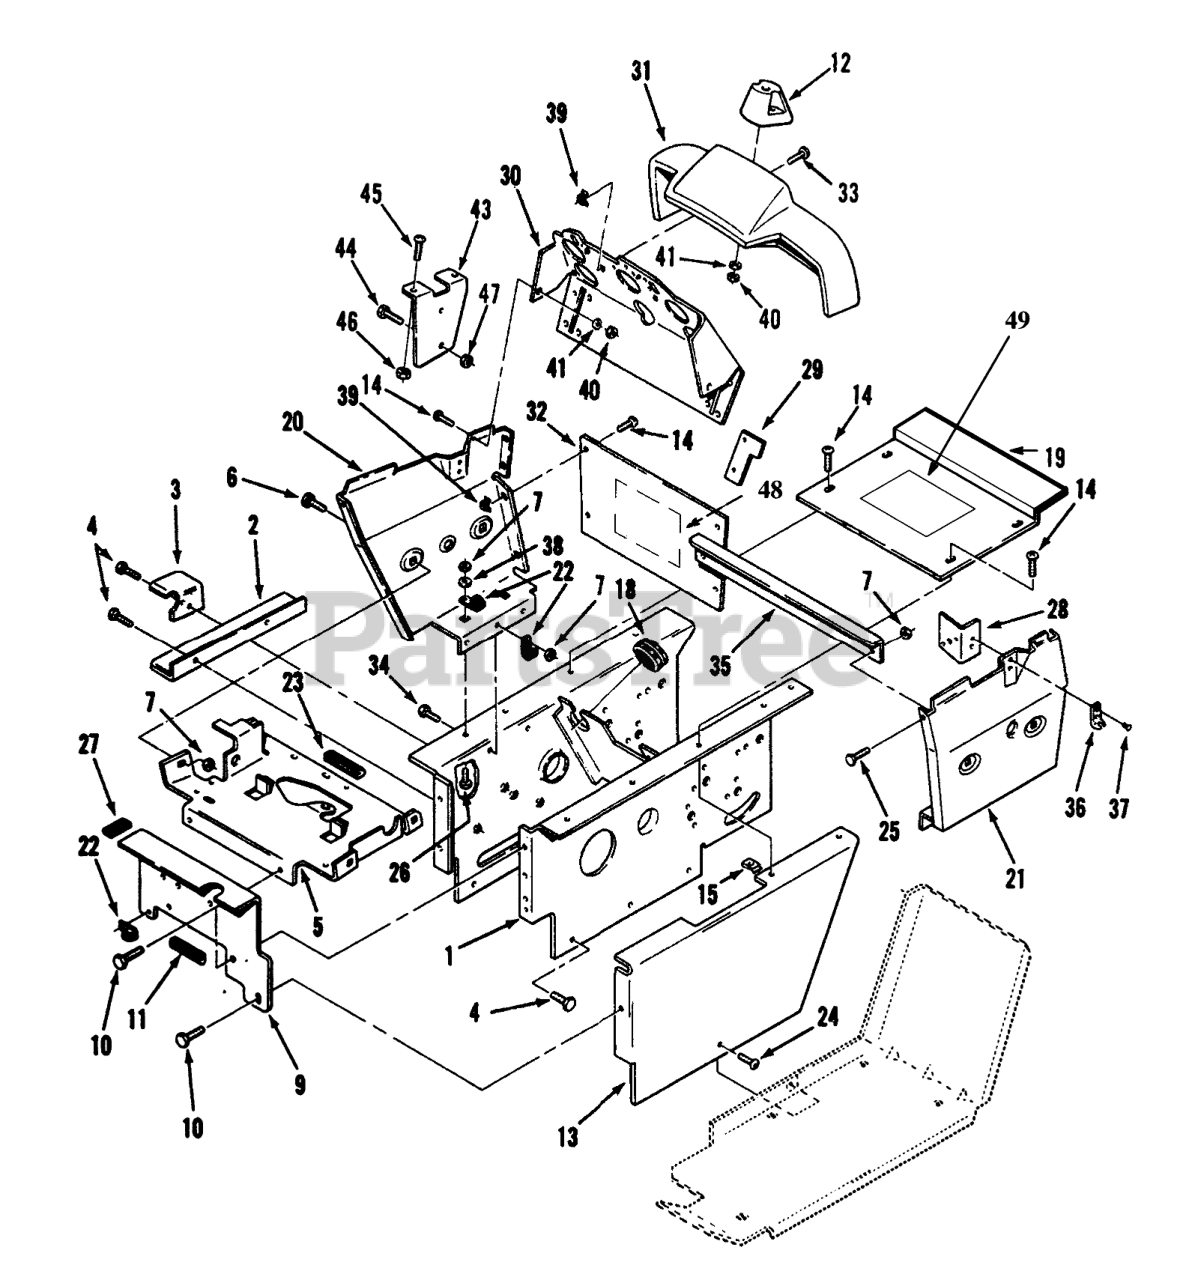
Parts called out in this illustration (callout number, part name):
1	Hoodstand
2	ANGLE-BELT GUARD B
3	Belt Bracket
4	SCREW
5	WLD-SUPPORTB
6	BOLT-CARR
7	NUT-LOCK, NI
9	Plate-Front
10	SCREW
11	EDGE TRIM 2" 102896
12	COVER-STEERING SHAFT
13	Cover-Side LH
14	Screw
18	GROMMET
19	Plate-Hoodstand, Top (Incl. Ref. #49)
20	Panel-RH
21	Panel-LH
22	CLIP
23	EDGE TRIM 5" OF 102896
24	Screw
25	SCREW-HH
26	CARRIAGE BOLT -4
27	EDGE TRIM-BULK
28	BRACKET-SWITCH SU
29	STOP-CHOKE
30	ASM-Panel
31	Kit-Console Cover (Contains #115620 5-Gauge Cover, #118410 Steering Cover, (4) 118780 Screw #6 Plastite, & (4) 920270 Washers)
32	Plate-Rear Hoodstand (Incl. Ref. #48)
33	Screw
34	SCREW-HH
35	STIFFENER-PANEL B
36	KEEPER-LATCH
37	RIVET-POP
38	WASHER-PLAIN
39	NUT-RETAINED
40	NUT-LOCK, NI
41	WASHER-FLAT
43	Bracket-Holder
45	SCREW-HH
46	Nut
47	NUT-LOCK, NI
48	DECAL - DANGER
49	DECAL-DANGER
